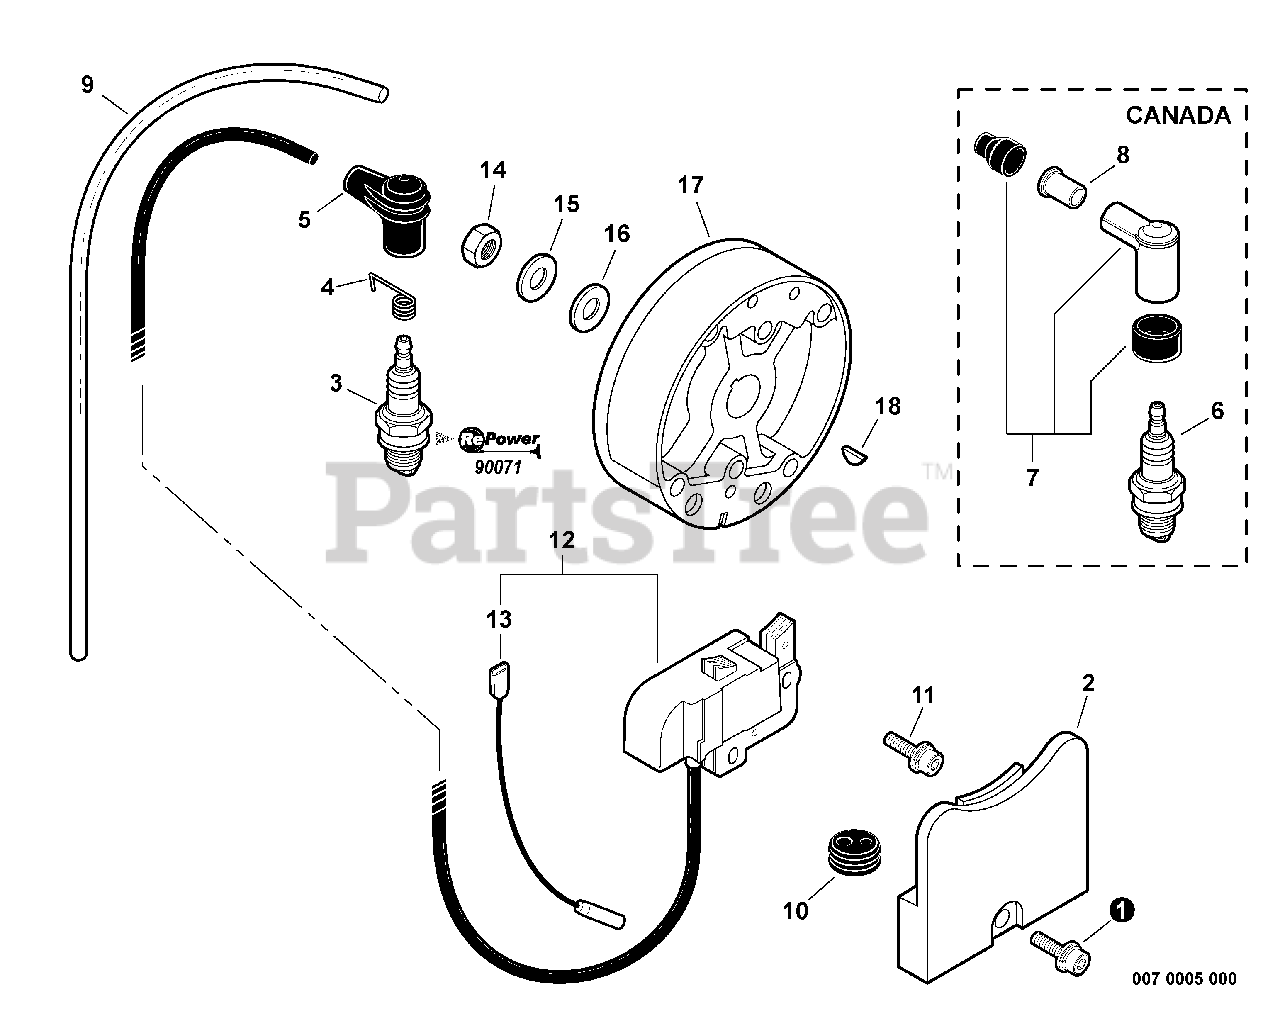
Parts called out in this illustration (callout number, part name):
1	SCREW - 5X22
2	COVER, DUST
3	SPARK PLUG -- BPM-8Y
4	TERMINAL, SPARK PLUG CAP
5	CAP, SPARK PLUG
6	SPARK PLUG -- BPMR-8Y
7	CAP, SPARK PLUG
8	ADAPTER, SPARK PLUG CAP
9	TUBE - VINYL
11	SCREW - 5X22
12	IGNITION COIL KIT
13	LEAD - IGNITION
14	NUT - 10
15	LOCKWASHER - 10
16	WASHER - 10
17	FLYWHEEL
18	KEY - 3X14
19	RePower TUNE-UP KIT
